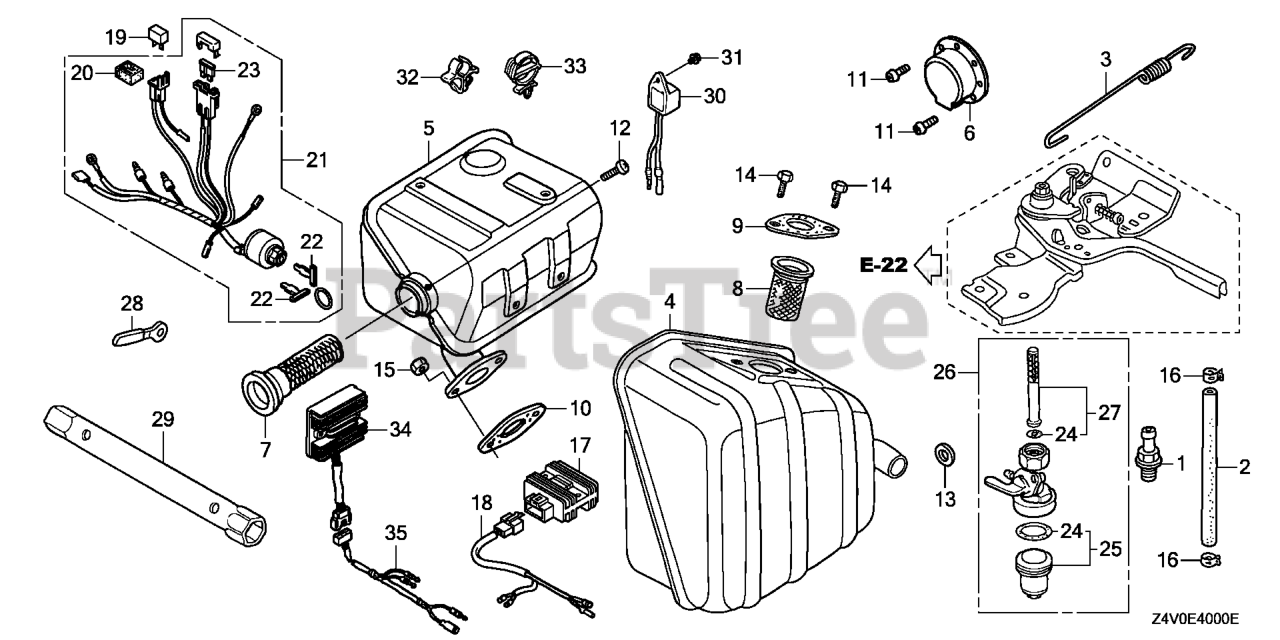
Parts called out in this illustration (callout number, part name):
1	JOINT, DRAIN
2	TUBE, DRAIN
6	CAP, MUFFLER
11	SCREW, TAPPING (4X6) (TO INSTALL OPTIONAL SPARK ARRESTER)
13	WASHER, DRAIN PLUG (10.2MM)
16	CLAMP, TUBE (D12)
19	RECTIFIER ASSY., SILICON (SHINDENGEN)
30	ALERT UNIT, OIL (CHONGQING LIHUA)
31	BOLT, FLANGE (6X8)
32	CLIP, CORD
33	STRAP, WIRE HARNESS (25MM) (BLACK)
